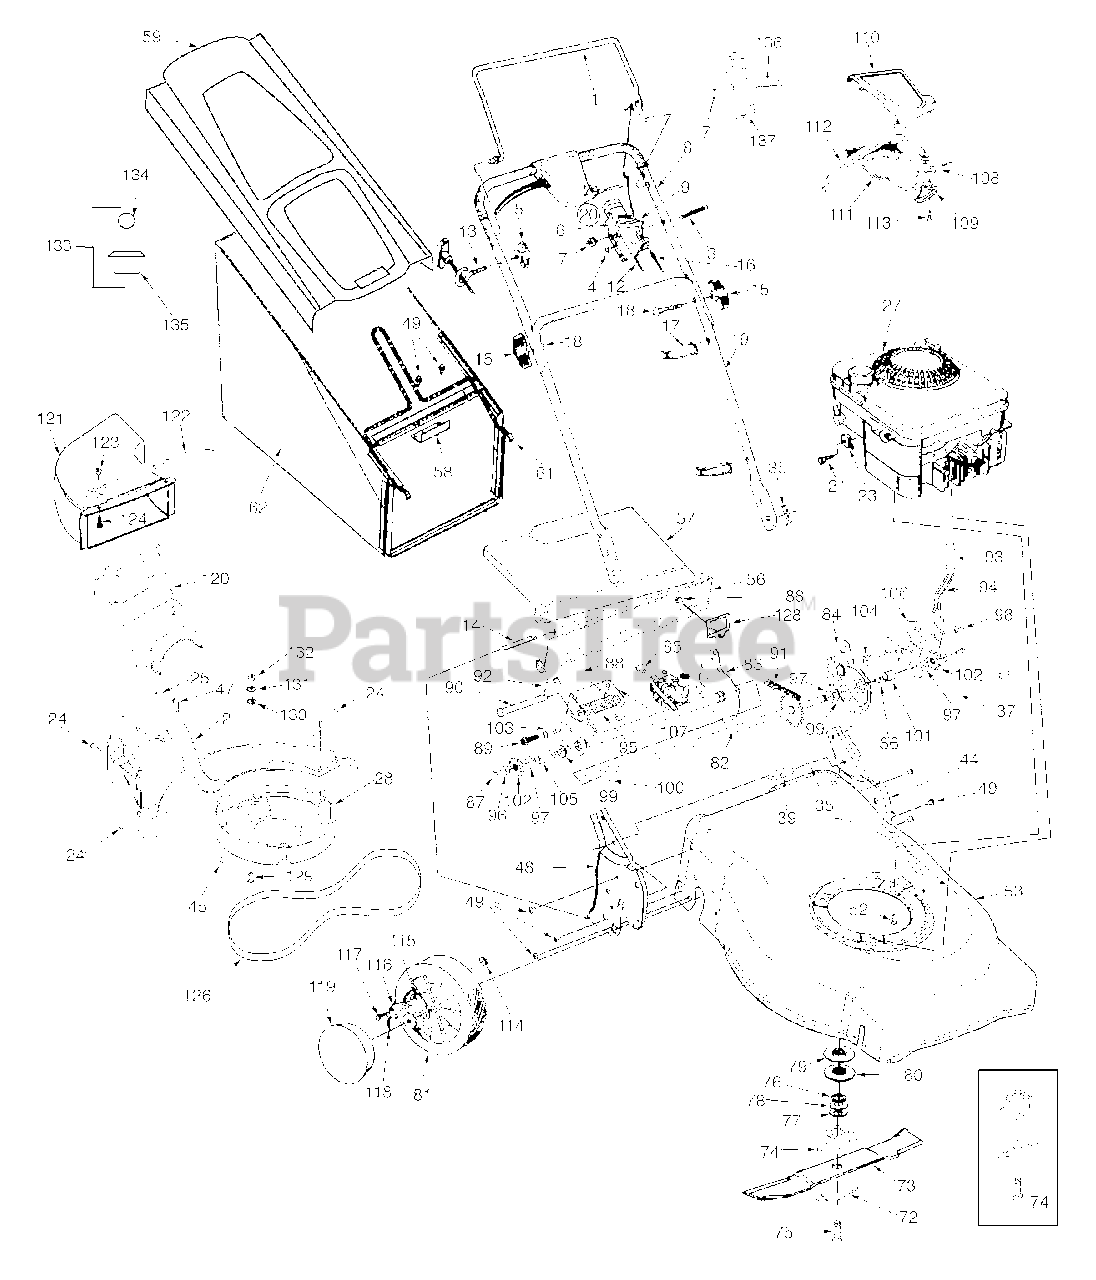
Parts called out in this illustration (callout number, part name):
2	Baffle
3	Oval C-Sunk Mach.-Scr.
4	Spr.Wash.66" I.D.
5	Handle Knob 1/4-20 Thd.
6	Throttle Body
7	Hex L-Nut 1/4-20
9	Throttle Lever
12	Throttle Control Wire-55"
13	Rope Guide
14	Wire-47" Lg.
15	Hand Knob
16	Control Cable-55"
17	Cable Tie
18	Cr.Hd. Bolt 5/16-18 x 2" Lg.
20	Throttle Box Comp.
21	Hex Self-Tap Scr. #10-32 x .62"
23	Cable Clamp (B&S)
24	Screw H.L. 12-24
25	Screw Mach. B Tapp.
27	Engine
28	Belt Cover
35	Int. Cotter Pin 5/15" Dia.
37	Pivot Rod
38	Spacer .385 I.D.
39	Torsion Spring L.H.
47	U-Nut
52	Hex L-Wash. Hd. Scr. 3/8-16 x 1"
62	Grass Bag - Black
72	Blade Bell Support
73	21" Mulching Blade w/Star
74	Blade Adaptor Kit w/Star
75	Hex Bolt 3/8-24 x 2.5 Lg.
76	Spacer
77	Fl. Wash. .885 x 1.85 x .06
78	Spr. Wash. .890 x .7 x .04
79	Pulley Half - Upper
80	Pulley Half - Lower
81	Wheel Assembly
82	Axle Assy: RR
86	Scr. TT 1/4-20
87	Hx Cap Screw 1/4-20
88	Scr. AB 1/4-20
89	Scr 3/8 - 16 x 1.25
90	Pin - Clv. .500 Dia. x.4.62 Lg.
91	Chain: Endless 48: .500P x 22 Lg.
92	Pin-Cotter .125 O.D. x .75
93	Grip - Foam
94	Spring Lever
95	Torsion Spring
96	Bell Washer .265 x 75 x .062
97	Wash.Flat .508 I.D. x 1.0 O.D.: .020
98	Nut - Shoulder .625 x .165 Lg.
99	Bearing - Flg Hex
100	Bearing - Flg. Hex
101	Bearing - Sleeve
102	Ratchet Wheel
103	Spacer - .385 x .625 x .700
104	Spacer - Shld. .385 I.D. x .715 Lg.
105	Spacer Slv. .520 I.D. x .950 Lg.
106	Pivot Arm
109	Mounting Cap
110	Control Cover - Upper
111	Control Cover - Lower
112	Lever
113	Scr. AB #10-12:.75 Lg.
114	Weld Top L. 1/4-20
115	Pawl Plate
117	Shldr. Scr. .340 x .285
118	Spring, Ratchet
119	Hub Cap
120	Mulch Plug
121	Chute Deflector
122	Chute Mounting Rod
123	Hex-L-Nut 1/4-20 thd.
124	Mach. Scr. 1/4-20
126	Belt
130	Lockwasher 1/4" Reg.
131	Fl. Wash. .271 x ..630 x .065
132	Nut 1/4-20
133	Flo Indicator Ass'y
134	Flo Indicator Ball
135	Flo Indicator Housing
136	Scr. 1/4-20:1.31 Lg.
137	Housing (w/o Throttle)
